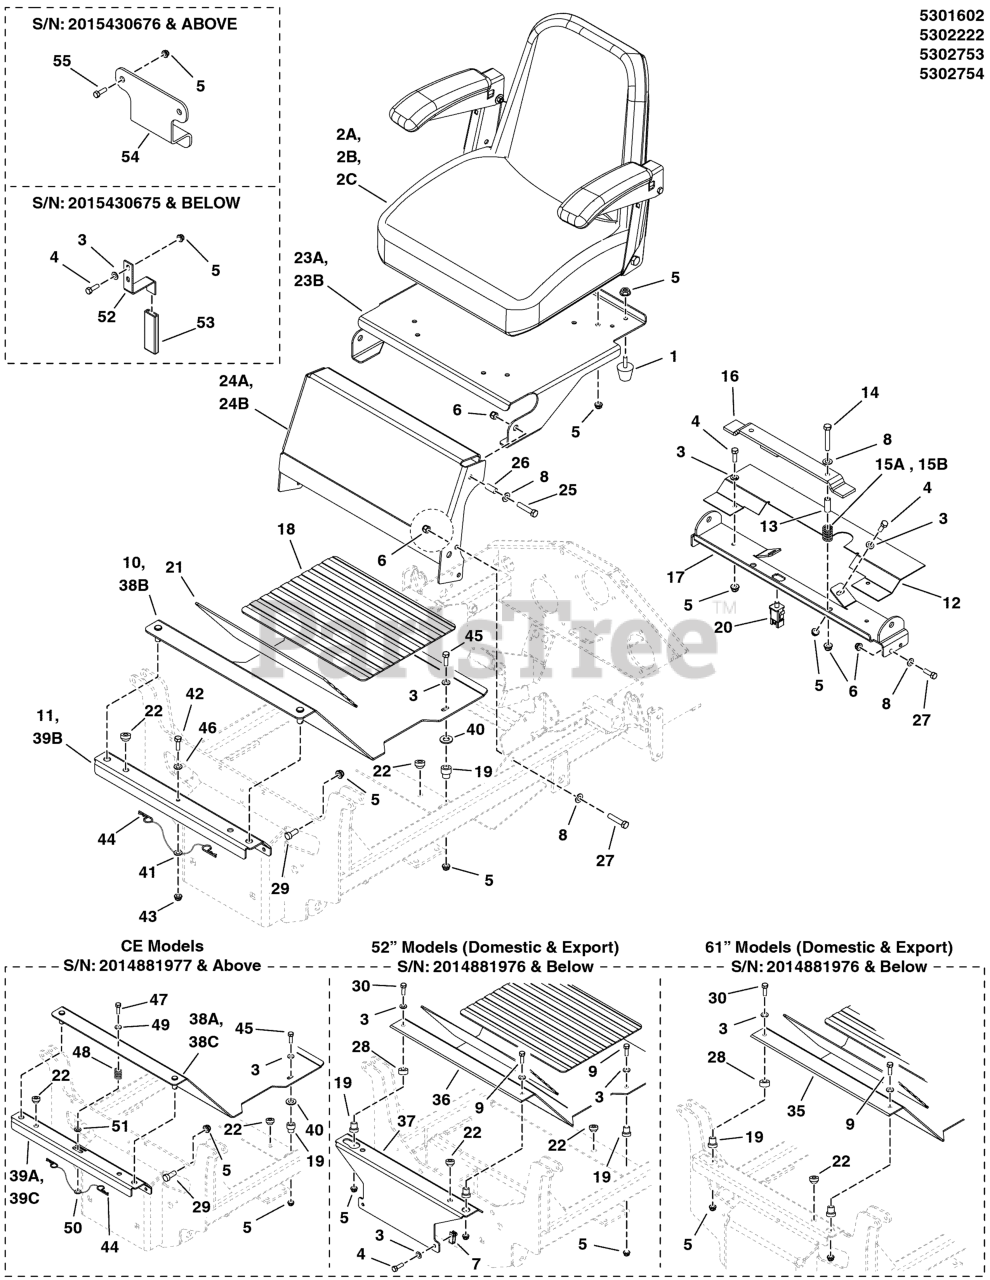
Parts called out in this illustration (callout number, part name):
1	BUMPER, RUBBER 5/16-18
3	WASHER, 5/16" SAE
4	BOLT, 5/16-18 X 1 GD5 YZ
5	NUT, 5/16-18 HEX NYLOCK FLANGE
6	NUT, 3/8-16 HEX NYLOCK FLANGE
7	NUT, 5/16-18 HEX NYLON LOCK
8	WASHER, 3/8 SAE
9	BOLT, 5/16-18 X 1-1/2 GD5 YZ
10	PLATE, FLOOR, IS2500
11	PLATE, FLOOR MOUNTING
12	GUARD, HYDRO BELT, IS2500 - RED
13	SPACER, .38 X .50 X 1.25, CZ
14	BOLT, 3/8-16 X 2, GD5, CZ
16	WELD, SEAT SWITCH, IS2500Z -RED
17	WELD, SEAT SUPPORT - RED
18	SAFETY WALK, 11.50 X 15.00
19	BUSHING, .38 X .88 X .73
20	SWITCH, PLUNGER, NO/NO SNAP-IN
21	SAFETY WALK, FLOOR REST, 17.13 X 6.00
22	MNT, VBRTN, RBBR
25	SCREW HEX HD 3/8-16X1.250 .141TH HD G5
26	SPACER, .38 X .50 X .27
27	BOLT, 3/8-16 X 1" GD5 CZ
28	SPACER, .390 X 1.00 X .188, YZ
29	BOLT, 5/16-18 X 3/4, CARRIAGE
30	BOLT, 5/16-18 X 1-3/4 GD5 YZ
35	PLATE, FLOOR, IS2500 - RED - 61
36	PLATE, FLOOR, IS2500 - RED - 52
37	WELD, FRONT FLOOR - RED
40	WASHER, .350 ID X .65 OD X .160 THK. YZ
41	WASHER, .34 X 1.25 X 10 GA
42	BOLT, 1/4-20 X 3/4 GD5 YZ
43	NUT, 1/4-20 HEX NYLOCK FLANGE
44	HAIRPIN COTTER LANYARD ASM, 8"
45	BOLT, 5/16-18 X 1-1/4 GD5 YZ
46	WASHER, 1/4 SAE
47	DZUS, 1/4 TURN FASTENER, D8X29MM
48	DZUS, EJECTOR SPRING
49	DZUS, CUPPED WASHER
50	DZUS, RECEPTACLE, CLIP-ON, D8
51	DZUS, RETAINER, PUSH-ON, SS
52	RETAINER, BATTERY - RED
53	GRIP, FOAM, 1/4 X 1 X 4.1
54	RETAINER, BATTERY - RED
55	BOLT, 5/16-18 X 1, CARRIAGE
56	PAD, RUBBER MOUNT
